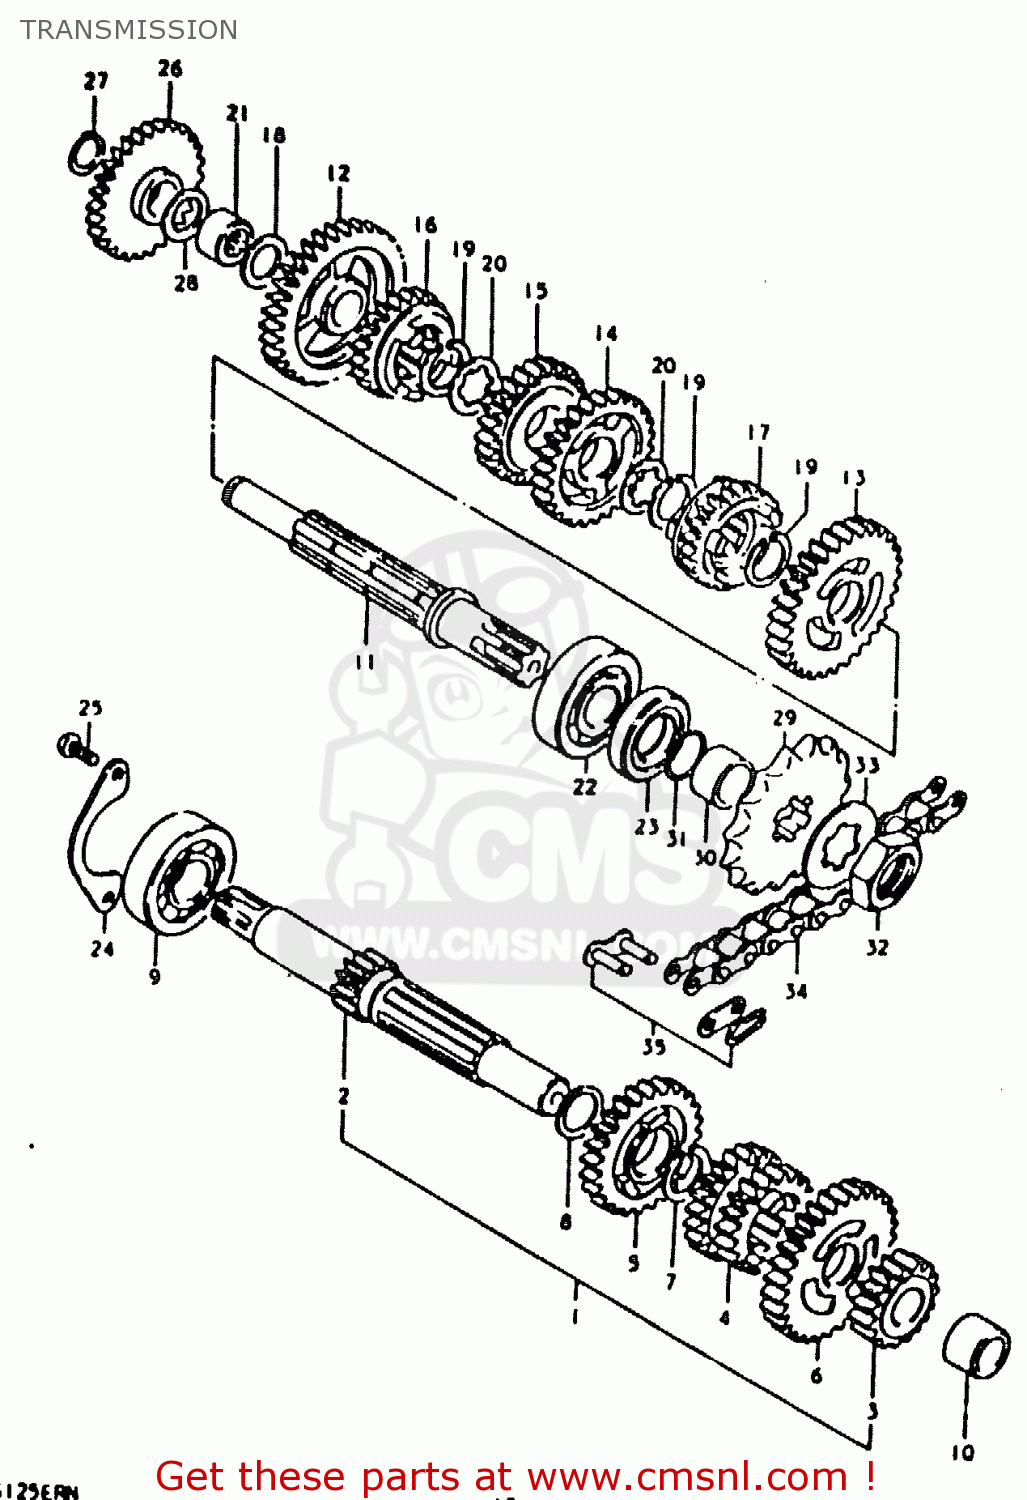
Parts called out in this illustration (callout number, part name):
1	SHAFT ASSEMBLY,COUNTER
2	SHAFT,COUNTER
3	GEAR,SECOND DRIVE
4	GEAR,THIRD/FOURTH DRIVE
5	GEAR,FIFTH DRIVE
6	GEAR,SIXTH DRIVE
7	CIRCLIP
8	WASHER
9	Bearing
10	BUSH(15X22X15)
11	SHAFT,GEAR SHIFT
12	GEAR,1ST DRIVEN
13	GEAR,SECOND DRIVEN
14	GEAR,THIRD DRIVEN
15	GEAR,FOURTH DRIVEN
16	GEAR,FIFTH DRIVEN
17	GEAR,SIXTH DRIVEN
18	WASHER,THRUST
19	CIRCLIP
20	WASHER,LOCK
21	BEARING(15X22X12)
22	Bearing
23	SEAL,OIL(25X40X7)
24	RETAINER,CNTR SHAFT BEARING
25	SCREW 6X12
26	GEAR,KICK STARTER IDLE
27	CIRCLIP,15MM
28	WASHER,THRUST
29	SPROCKET,ENGINE
30	SPACER(20X25X12.5)
31	O RING(D:1,ID:19.5)
32	NUT
33	WASHER,LOCK
34	CHAIN ASSEMBLY,DRIVE
35	JOINT ASSEMBLY,CHAIN
